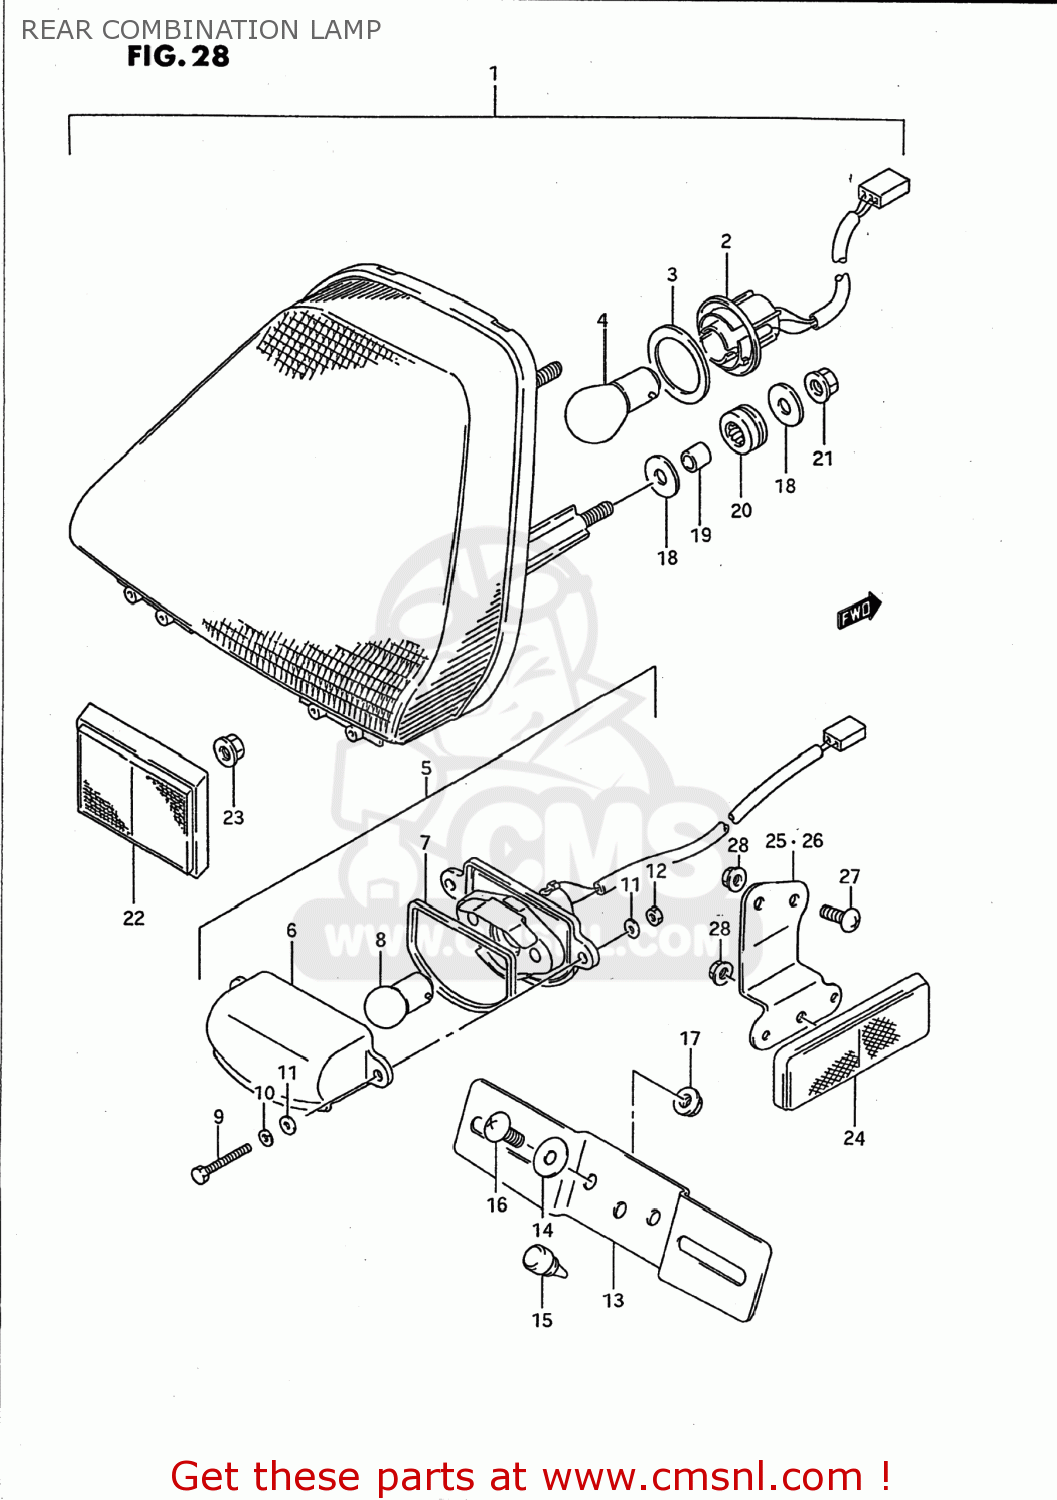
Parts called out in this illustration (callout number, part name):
1	LAMP ASSY,RR COMBINATION
2	SOCKET
3	CUSHION,RUBBER
4	BULB(12V21/5W,BF141-49642A)
5	LAMP ASSEMBLY,LICENSE
6	LENS,LICENSE LAMP
7	GASKET,LICESE LAMP (NAS)
8	BULB(12V8W)
9	BOLT
10	WASHER,LOCK
11	WASHER
12	NUT
13	BRACKET,LICENSE PLATE
14	WASHER(6.5X20X1.6)
15	CUSHION
16	SCREW
17	NUT
18	WASHER (6.5X20X1)
19	SPACER (6.1X8X9.5)
20	CUSHION
21	NUT
22	REAR ASSEMBLY,REAR
23	NUT
24	REFLECTOR ASSEMBLY,REAR
25	BRACKET,RR SIDE RR,R
26	BRACKET,RR SIDE RR,L
27	SCREW 5X12
28	NUT
